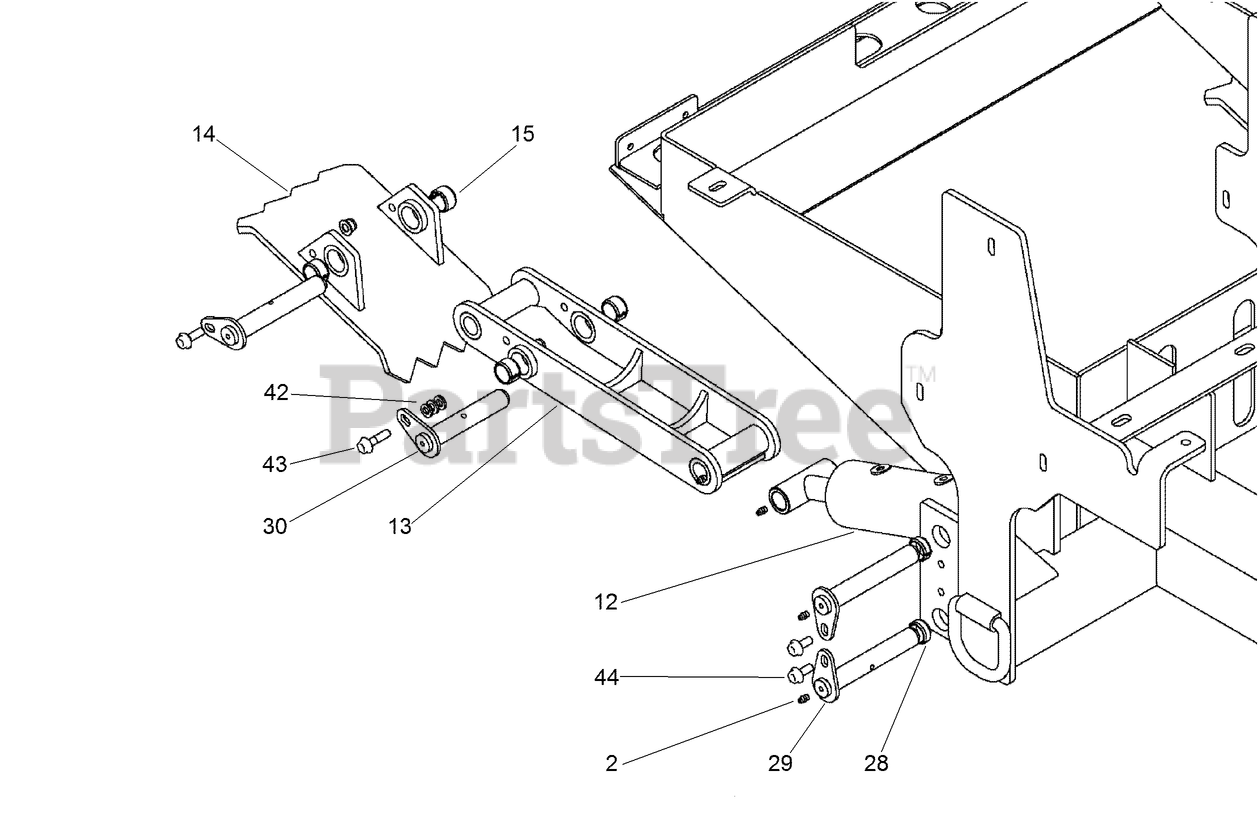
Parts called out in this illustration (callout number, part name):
2	FITTING-Lube 1/4-28 Tpr SAE-LT .54 Long
12	HYD CYLINDER ASM
13	WELDMENT - Stabilizer Leg
14	WELDMENT - Stabilizer Foot
15	BUSHING-SPRING
28	BUSHING-SPRING
29	PIN-FLAG
30	PIN-FLAG
42	WASHER - 0.406 x 0.750 x 0.119 in CST ZND
43	SCREW-HHF
44	SCREW-FLANGE
